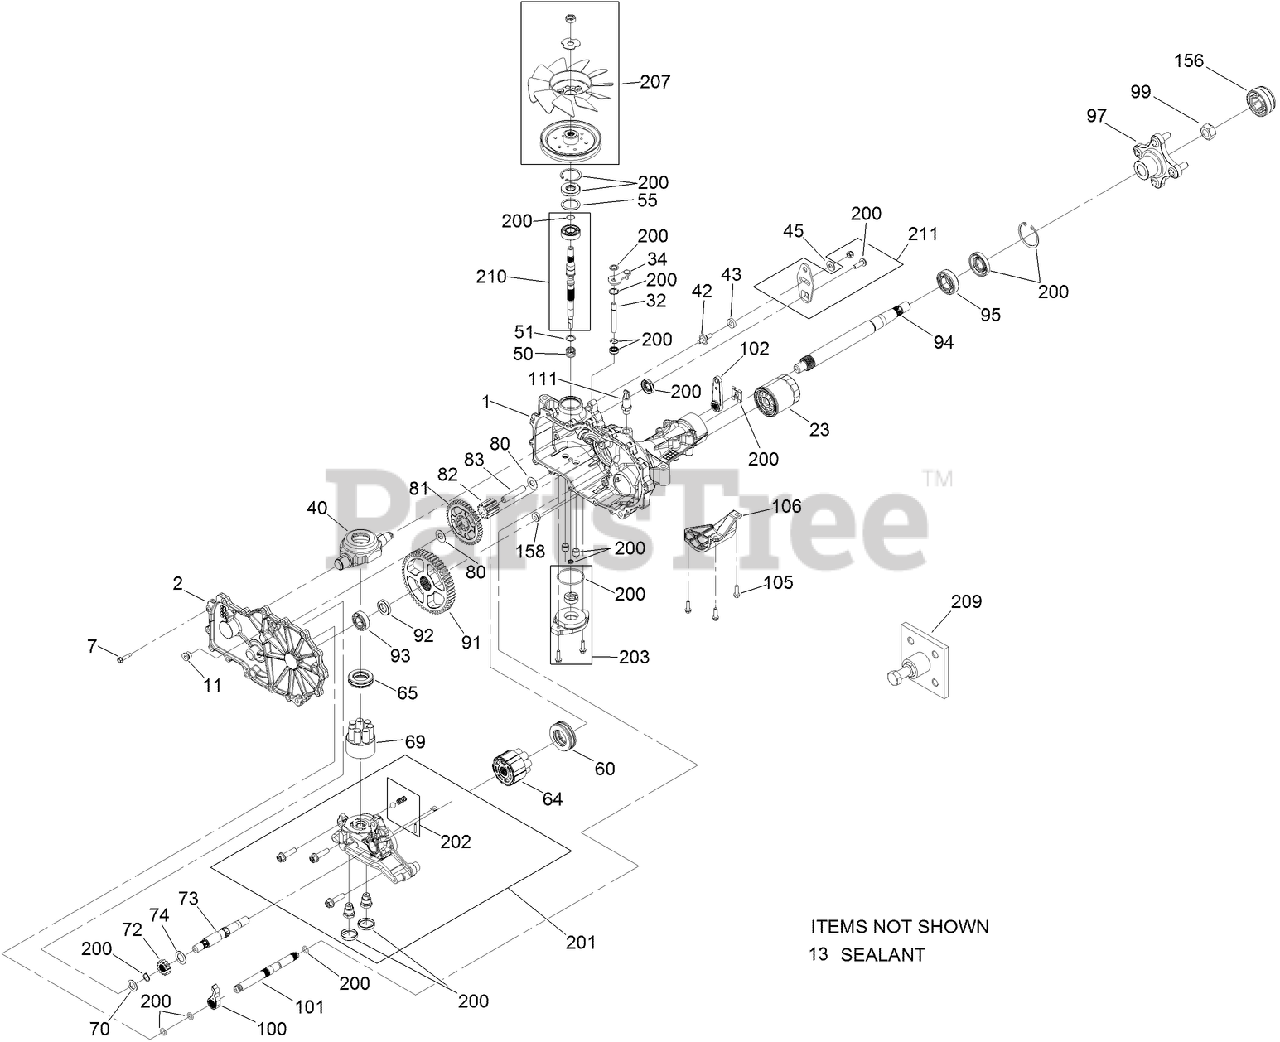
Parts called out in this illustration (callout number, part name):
1	RH MAIN HOUSING KIT
2	RH SIDE COVER KIT
7	SCREW-HHF
11	PLUG-THREAD, STRAIGHT
23	ELEMENT-OIL FILTER, HYD
32	ROD-BYPASS
34	ARM-BYPASS
40	SWASHPLATE-TRUNNION
43	PUCK-FRICTION
45	WASHER
50	SPRING-COMPRESSION
51	WASHER
55	SPACER
60	BEARING-THRUST
64	MOTOR CYLINDER BLOCK KIT
65	BEARING-THRUST, PLASTIC CAGE
69	7 PISTON BLOCK ASM
70	WASHER-FLAT
72	GEAR-13T
73	SHAFT-MOTOR
74	WASHER
80	WASHER
81	GEAR-46T
82	GEAR-11T
83	PIN-JACKSHAFT
91	GEAR-54T
92	SPACER
93	BEARING-BALL
94	SHAFT-AXLE
95	BEARING-BALL
97	HUB KIT
99	NUT-HUB
100	PAWL-BRAKE
101	BRAKE SHAFT KIT
102	HANDLE-BRAKE
105	SCREW-HF
106	GUARD-FILTER, RH
111	ADAPTER-STRAIGHT
156	COVER-NUT, AXLE
158	MAGNET-RING
200	SEAL KIT
201	RH CENTER SECTION KIT
202	CHARGE RELIEF KIT
203	CHARGE PUMP KIT
207	FAN AND PULLEY KIT
209	PULLER-HUB, 4 BOLT
210	INPUT SHAFT KIT
211	CONTROL ARM KIT
